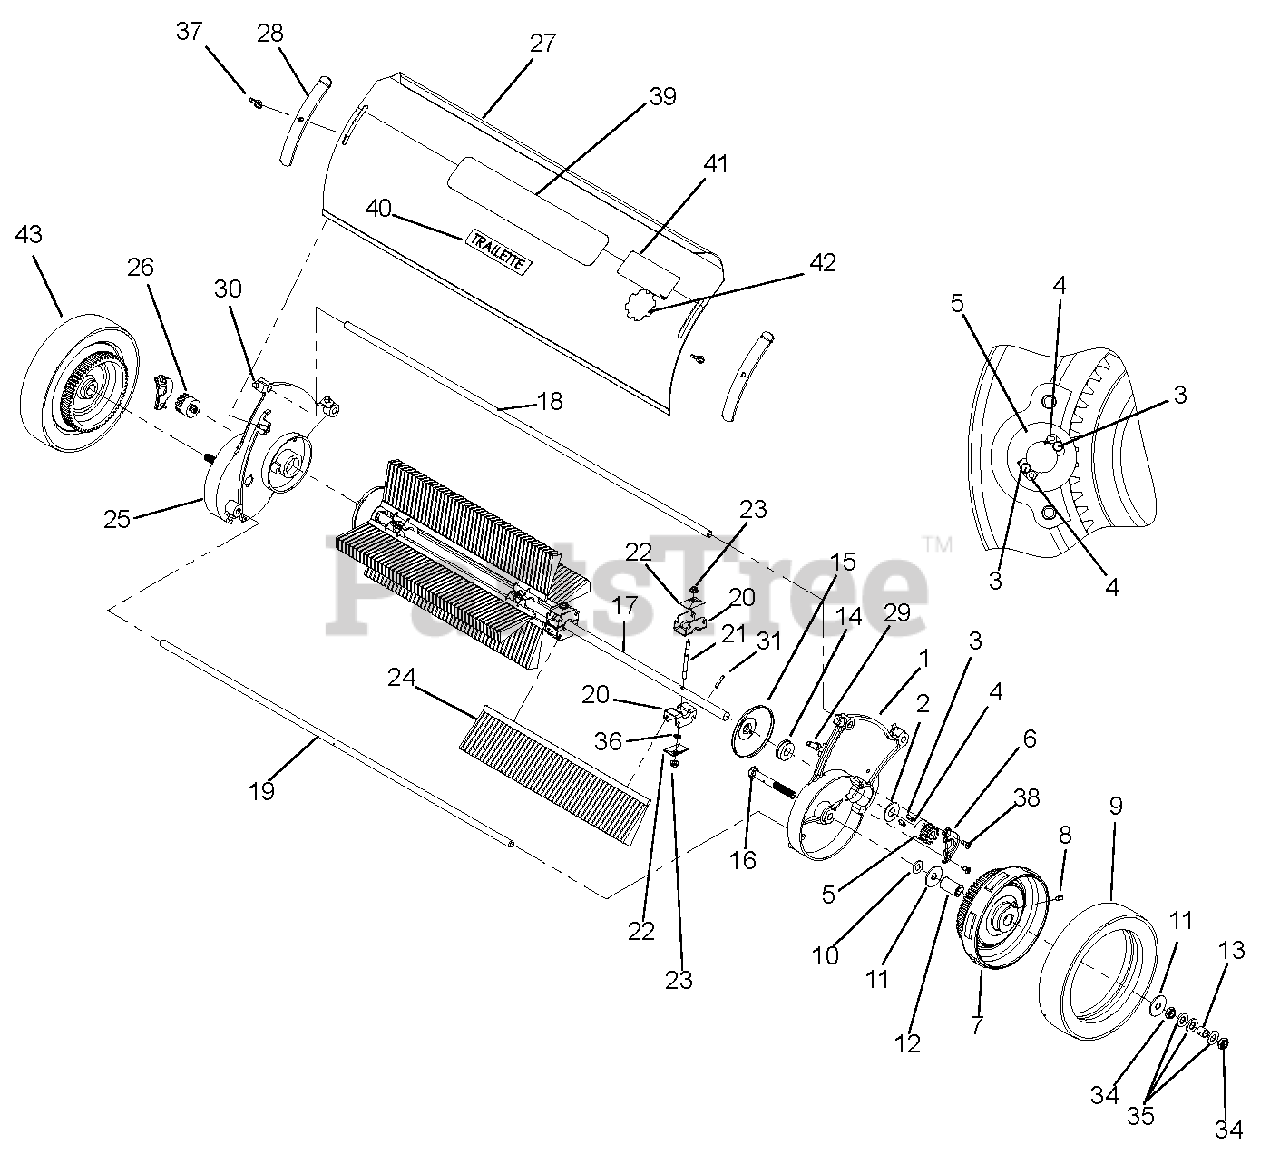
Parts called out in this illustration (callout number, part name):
1	Side Plate, Left Hand
2	Washer, Flat .656 x 1.50 x .06
3	Dowel Pin, .1875 OD x .4375
4	Pawl Spring, .188 x .049 W x .438
5	Pinion, Left
6	Casting, Cover Pinion
7	Wheel, Drilled
8	Grease Fitting, 3/16
9	Tire Only
10	Washer, Fiber
11	Washer, Flat .516 x 1.625 x .075
13	Spacer, Axle
14	Bearing, Flanged Radial
15	Dust Cover
16	Bolt, Axle 1/2-20 x 4 Special Gr 2 1-7/8 Head
17	Reel Shaft, Plated
18	Tie Rod, Top 1/2 Round
19	Tie Rod, Front 1/2 Round
21	Plated Stud, Zinc
22	Clamp, Brush Strip
23	Nut, Flanged .25-20
24	Sweeper Brush
25	Side Plate, Right Hand
26	Pinion, Right
27	Hood with Decals, Parker
28	Clamp, Hood
29	Bolt, Hex .31-18 x 1.00 Gr 5 YWZC
30	Set Screw, Square Head
31	Roll Pin, 3/16 x 1-3/4
32	Basket Bottom and Bag
34	Nut, Jam Nylok 1/2-20 Gr 2 YWZC
35	Washer, Flat Steel .531 x 1.06 x .95 YWZC
36	Nut, Speed 1/4
37	Nut, Wing 5/16-18 Steel Plate
38	Screw, Flat Head 1/4-20 x 5/8
39	Decal, Parker
40	Decal, Trailette
41	Decal, Danger Read Manual
42	Decal, Parker Small Heritage
43	Sweeper Tire/Wheel Assembly (includes items 7, 8 & 9)
44	Pinion Kit (includes items 3, 4, 5 & 26)
